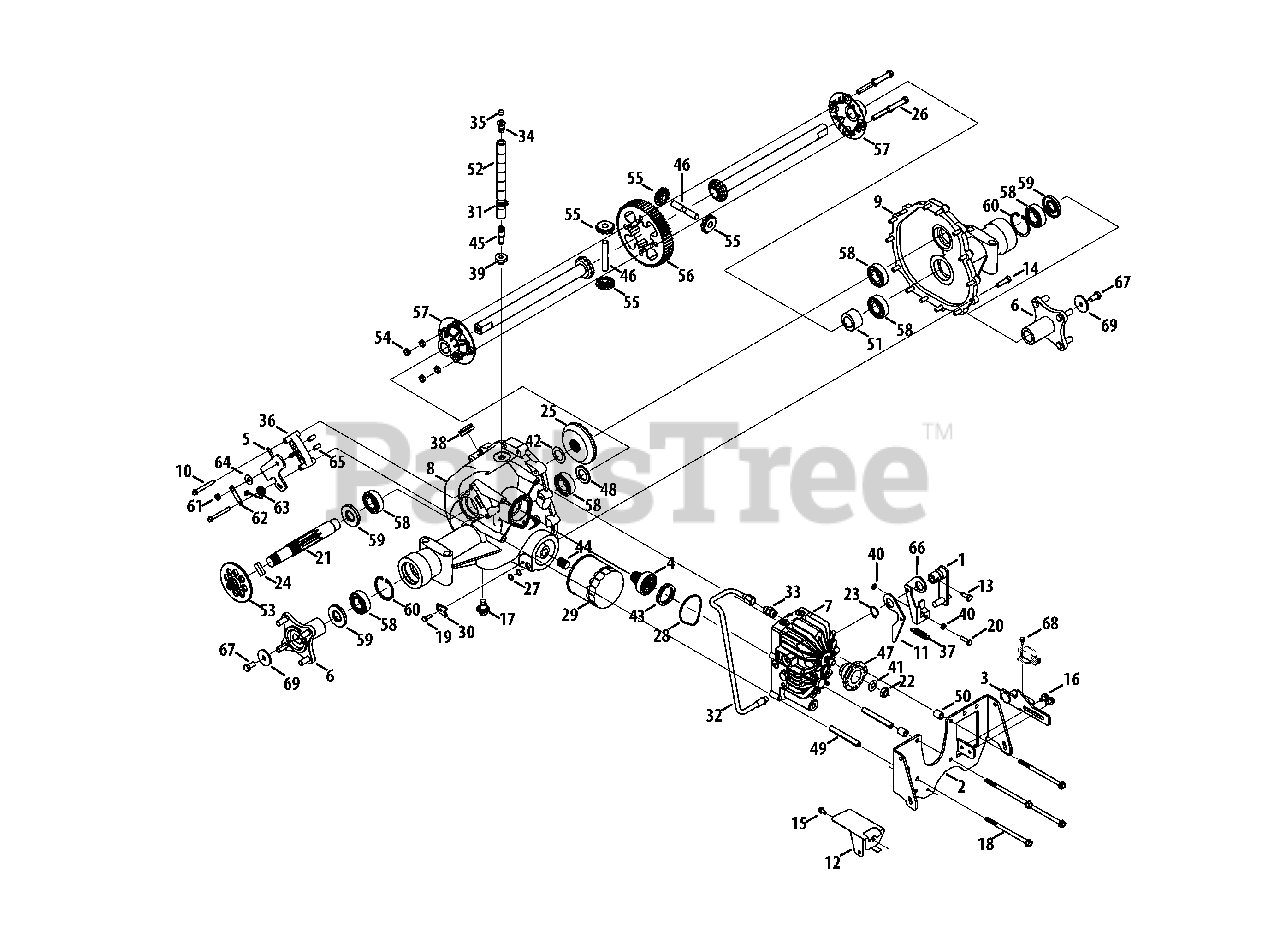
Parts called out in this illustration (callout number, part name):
1	Neutral Return Arm Assembly
2	Torq Bracket Assembly
3	Neutral Return Arm Assembly
4	Pinion Gear, 13T
5	Brake Arm Actuator
6	Wheel Hub Assembly
7	Pump Assembly
8	RH Housing
9	LH Housing
10	Hex Washer Screw, 1/4-20 x 2.375
11	Neutral Arm, LH
13	Hex Screw, 5/16-24 x .625
14	Hex Lock Screw, 5/16-18 x 1.25
15	Hex Washer Screw, 1/4-20 x .500
16	Hex Washer Screw, 5/16-18 x .500
17	Plug Screw, M14 x 1.5 x .827
18	Hex Washer Screw, 5/16-18 x 5.350
19	Hex Screw, 1/4-20 x .75
20	Hex Screw, 1/4-20 x 1.00
21	Output Shaft, 9T
22	Jam Lock Nut, 1/2-20
23	Retaining Ring, .875
24	Brake Pad
25	Bevel Gear, 54T
26	Hex Screw, 3/8-16 x 2.00
27	0-Ring, .426 x .566 x .070
28	Gland Seal
29	Oil Filter
30	Tube Clamp, .500
31	Fuel Clamp
32	Hydro Pick-Up Tube
33	Straight Fitting
34	Plastic Vent
35	Plastic Vent Cap
36	Brake Yoke
37	Extension Spring, .50 x 1.98
38	Rubber Grommet, .750 x 1.063 x .4375
39	Grommet, .362 x .56 x .63
40	Jam Nut, 1/4-20
41	Bell Washer, .525 x 1.00 x .050
42	Thrust Washer, 1.007 x 1.542 x .03
43	Spring Washer, 1.595 x 2.011 x .030
44	Filter Nipple Fitting
45	Tube Fitting, .500
46	Shaft, .500 x 3.005
47	Hydro Pump Adaopter
48	Axle Spacer, 1.007 x 1.665 x .141
49	Hydro Spacer, .323 x .443 x 3.51
50	Hydro Spacer, .323 x .600 x .740
51	Axle Spacer, 1.007 x 1.665 x .989
52	Fuel Line, 1/2
53	Disc Brake
54	Jam Lock Nut, 3/8-16
55	Miter Gear
56	Spur Gear
57	RH Housing Differential
58	Ball Bearing, 1 x 52 x 15
59	Oil Seal, 1.00 x 2.047 x .2755
60	Retainer Ring
61	Hex Lock Nut, 5/16-24
62	Anti-Rotation Brake Bracket
63	Torsion Spring, .75 x 3
64	Flat Washer, .343 x .880 x .062
65	Brake Actuator Pin
66	Neutral Arm
67	Hex Cap Screw, 3/8-16 x .750
68	Shoulder Screw, 10-32 x .500
69	Flat Washer, .390 x 1.50 x .134
